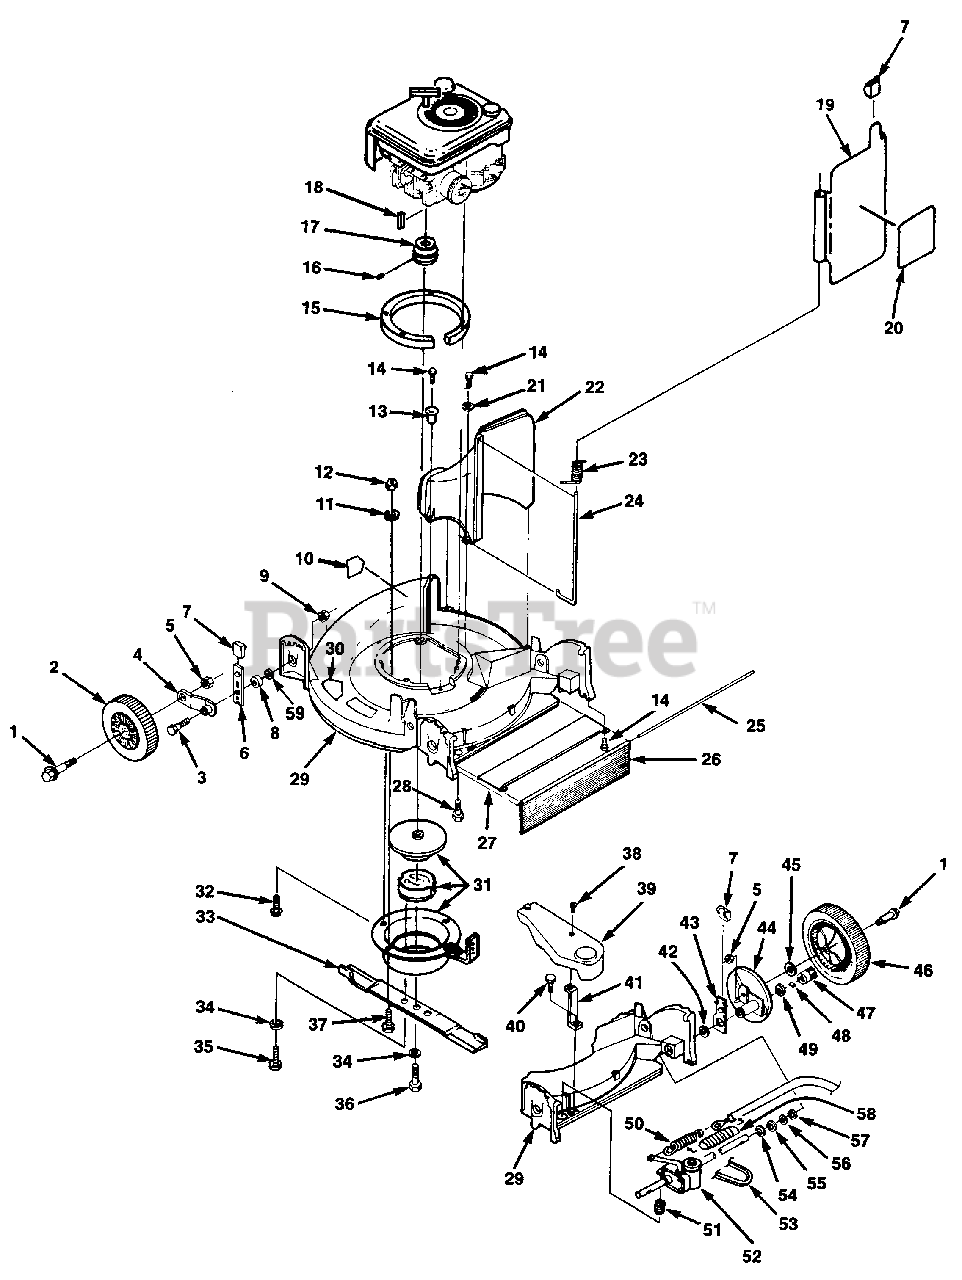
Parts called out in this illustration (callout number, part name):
1	BOLT- Axle
2	WHEEL & TIRE ASSY.
3	BOLT- Ht. adj.
4	WHEEL- Adjuster arm
5	NUT- (3/8-16)
6	SPRING
7	KNOB- Index spring
8	SPACER- Ht. adj.
9	NUT- Flange (5/16-18)
10	DECAL- Warning
11	WASHER- Lock (5/16")
12	NUT- Hex (5/16-18)
13	STIMPSON EYELET
14	SCREW- (1/4-20 x 3/4")
15	RING- Engine
16	SCREW- Set (1/4-20 x 3/8")
17	PULLEY- Drive
18	KEY- Woodruff #61 (5/8 x 3/16")
19	DOOR- Chute
20	DECAL- Door
21	WASHER- Plain (1/4")
22	CHUTE-
23	SPRING- Chute door
24	PIN- Hinge
25	ROD- ZP drag flap
26	FLAP- Drag
28	SCREW- Hex hd. sims (3/8-16 x 2 1/2")
29	DECK ASSY.
30	DECAL- Foot pad
31	BLADE/BRAKE/CLUTCH
32	SCREW- (5/16-18)
33	BAR- Cutter (21")
34	WASHER- Lock hvy. (3/8")
35	SCREW-(3/8-16 x 1")
36	SCREW-(3/8-24 x 2")
37	SCREW-(5/16-18 x 3")
38	SCREW-(1/4-20 x 3/4")
39	COVER-Drive
40	SCREW-Hex (#10-16)
42	SPACER- Rear hgt. adj.
44	DRIVE WHEEL SUPPORT ASSY.
46	WHEEL & TIRE
47	PINION- Ht. (R.H.)
48	PAWL- Ht. Pinion
50	SPRING- Extension
51	SPRING- Compression
52	GEAR REDUCER ASSY.
53	BELT- Drive
54	RING- Eaton
58	COVER- Spring
59	WASHER- Flat (5/16")
